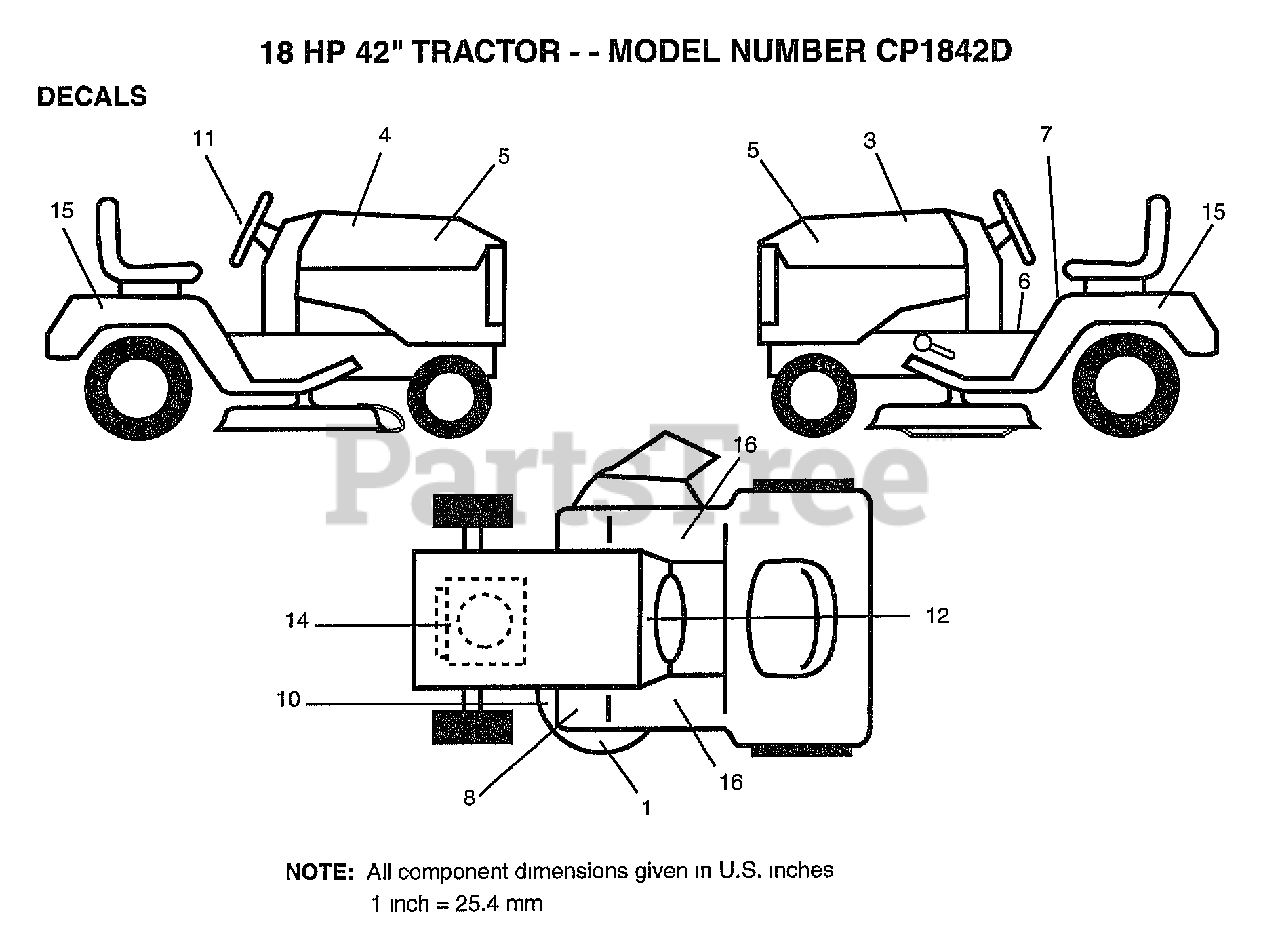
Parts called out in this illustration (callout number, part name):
4	DECAL HOOD STRIPE RH
5	CHASSIS DECAL
6	DECAL BRAK PARK
7	DECAL
10	DECAL.V.BELT
11	DECAL.WHL.STRG.
12	DECAL.DASH.INST.
14	DECAL.ENG.272757
15	DECAL.FEND.QUICK.
16	FOOTREST PAD
